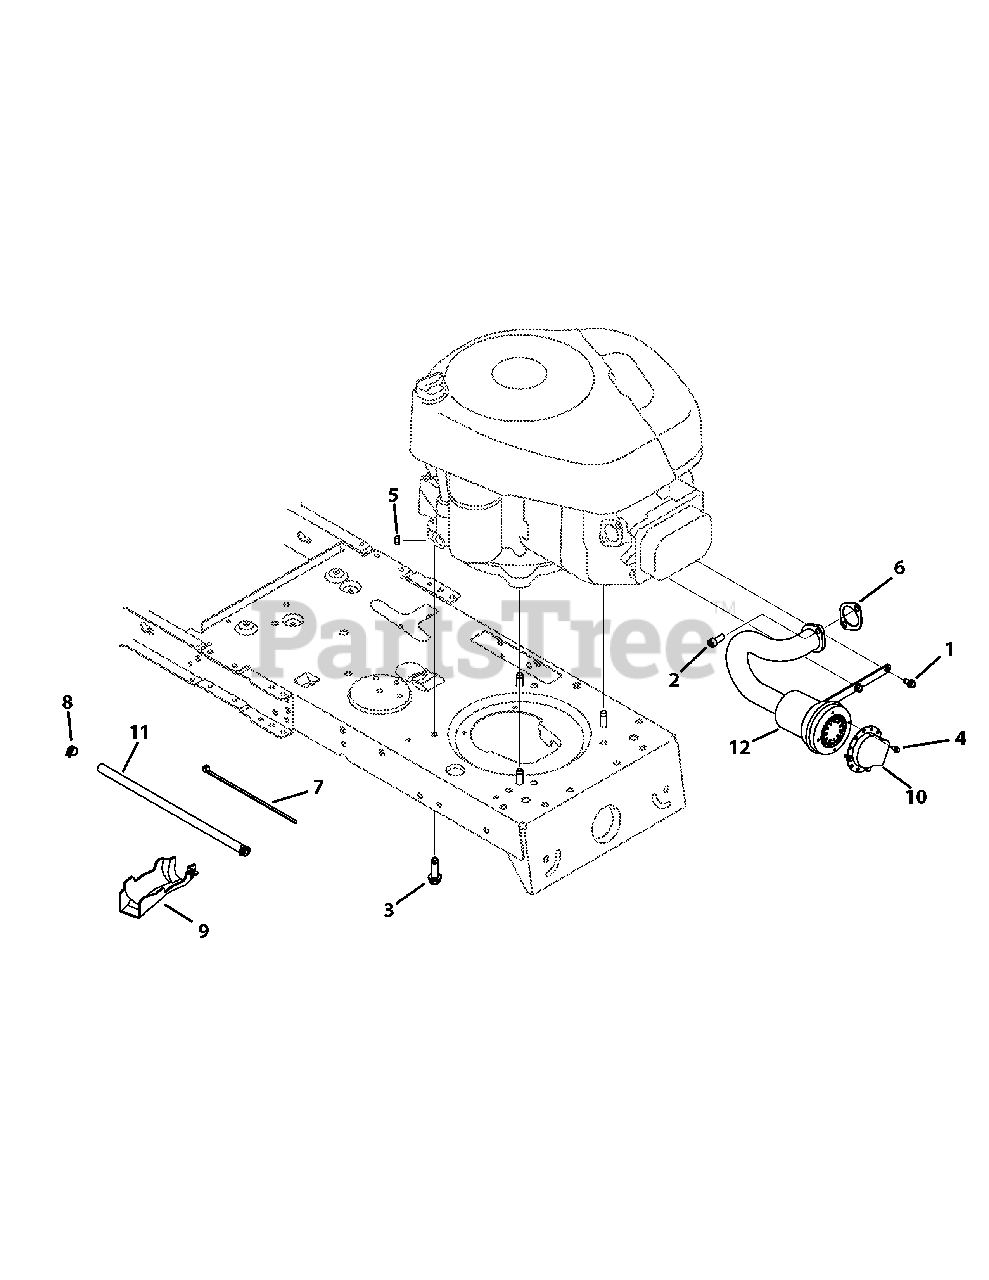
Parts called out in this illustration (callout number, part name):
1	Hex Wash S-Tapp Scr 1/4-20 x .50
2	Socket HD Cap Scr. 5/16-18 x .75
3	Hex Wash S-Tapp Scr 3/8-16 x 1.0
4	Hex Wash HD AB S-Tapp Scr #8-.50
5	Sems Nut 1/4-20
6	Exhaust Gasket
7	Cable Tie
8	Hose Clamp
9	Oil Drain Sleeve
10	Muf fler Deflector
11	Fuel Line
12	Muffler, Bug
